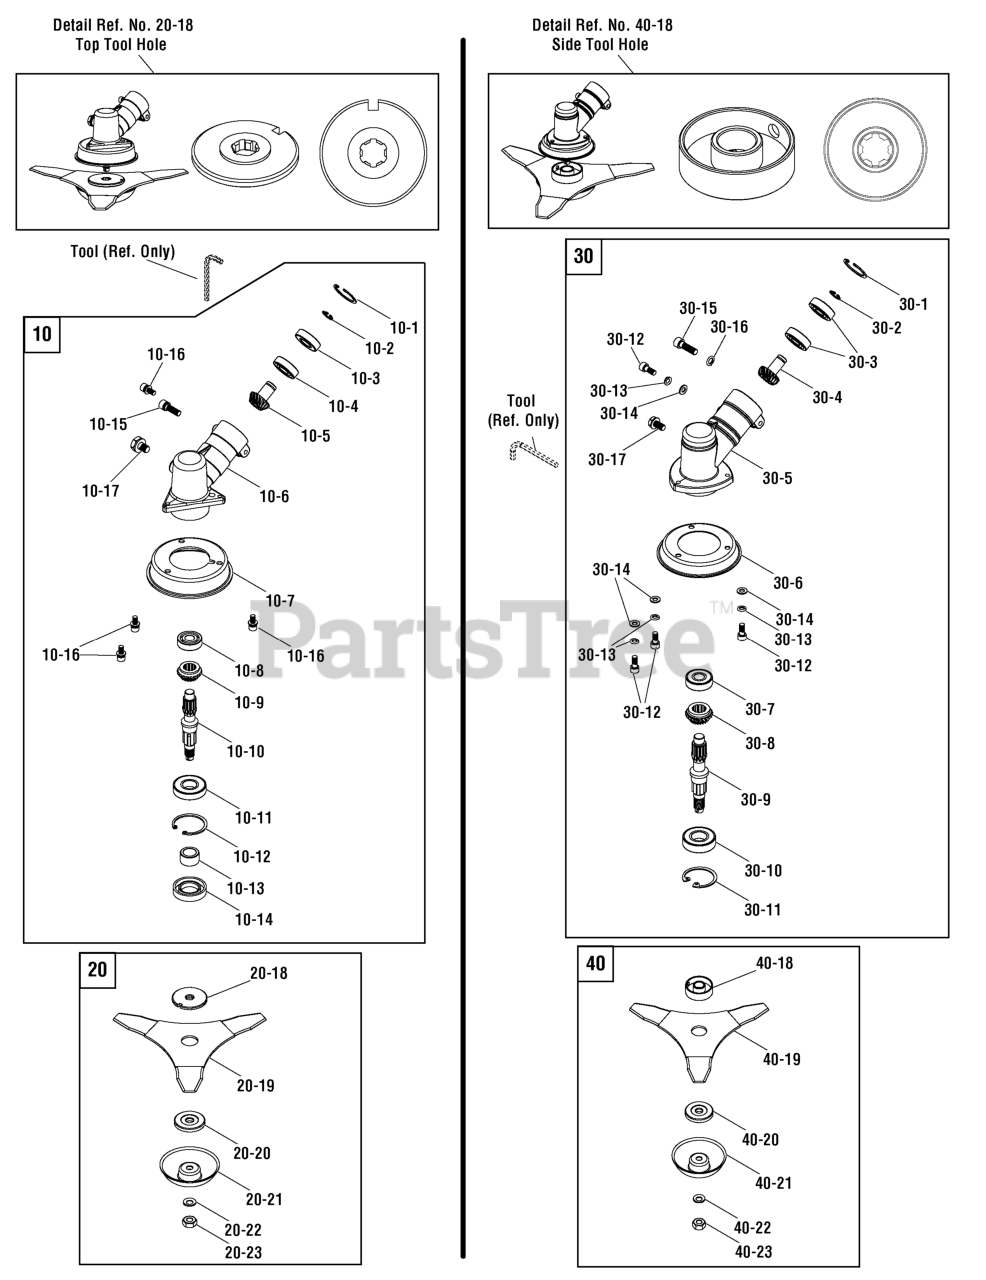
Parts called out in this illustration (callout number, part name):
10	KIT, GEARBOX (Top lock hole)
10-5	PINION
10-6	GEARBOX
10-7	COVER, Blade
10-10	SHAFT, Spline
10-13	SEAL, Oil
10-14	SLEEVE, Spline
10-17	BOLT, M8 x 12
20	KIT, BLADE
20-18	GASKET, Spline
20-20	HOLDER
20-21	PROTECTOR, Blade
20-22	WASHER, Wave, 10
30	KIT, GEARBOX (Side lock hole)
30-4	PINION
30-5	GEAR BOX
30-6	COVER, Blade
30-9	SHAFT, Spline
30-12	BOLT, M5 x 12
30-13	WASHER, Spring, 5
30-14	WASHER, Flat, 5
30-15	BOLT, M6 x 20
30-16	WASHER, Spring, 6
40	KIT, BLADE
40-18	GASKET, Spline
40-20	HOLDER
40-21	PROTECTOR, Blade
40-22	WASHER, Wave, 10
